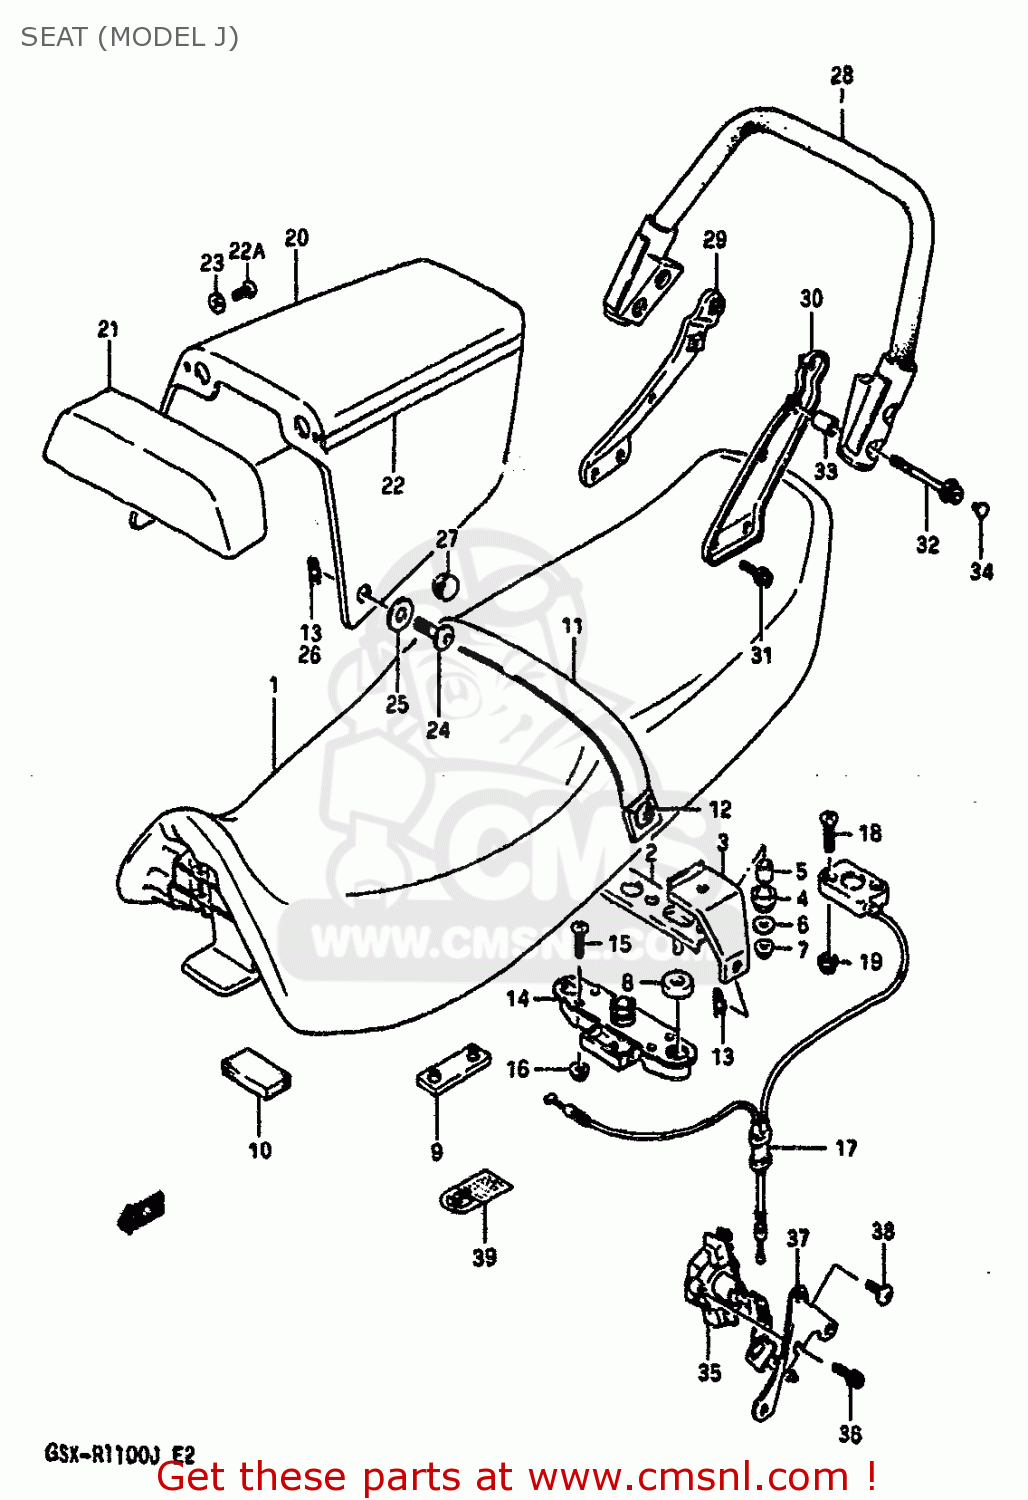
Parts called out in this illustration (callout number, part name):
1	SEAT ASSEMBLY
2	STRIKER,SEAT LOCK
3	PLATE,SEAT GRIP BAND
4	CUSHION
5	SPACER
6	WASHER
7	NUT
8	CUSHION
9	CUSHION
10	CUSHION
11	BAND,SEAT GRIP
12	BOLT
13	CLIP
14	LOCK ASSY,SEAT STRIKER
15	SCREW
16	NUT
17	BRACKET,SEAT SUPPORT RR
18	SCREW
19	NUT
20	BOX SET,SEAT TAIL
21	BACKREST,SEAT
22	TAPE SET,SEAT TAIL BOX
22A	SCREW, CENTER
23	WASHER (6.5X18X1.6)
24	BOLT
25	WASHER(10X25X3.2)
26	CLIP
27	CAP,SEAT TAIL COVER
28	HANDLE,PILLION RIDER
29	PLATE,PILLION HANDLE,R
30	PLATE COMP,PILLION HANDLE
31	BOLT
32	BOLT 5X10
33	SPACER (8.6X13.8X21.5)
34	CAP(OD:10)
35	LOCK SET
36	PLUG ,6X20
37	BOLT
38	BOLT
39	CAP(OD:10)
40	SPACER (8.6X13.8X21.5)
41	LOCK SET
42	PLUG ,6X20
43	BRACKET,SEAT LOCK
44	SCREW 6X12
45	LABEL,ASBESTOS WARNING
